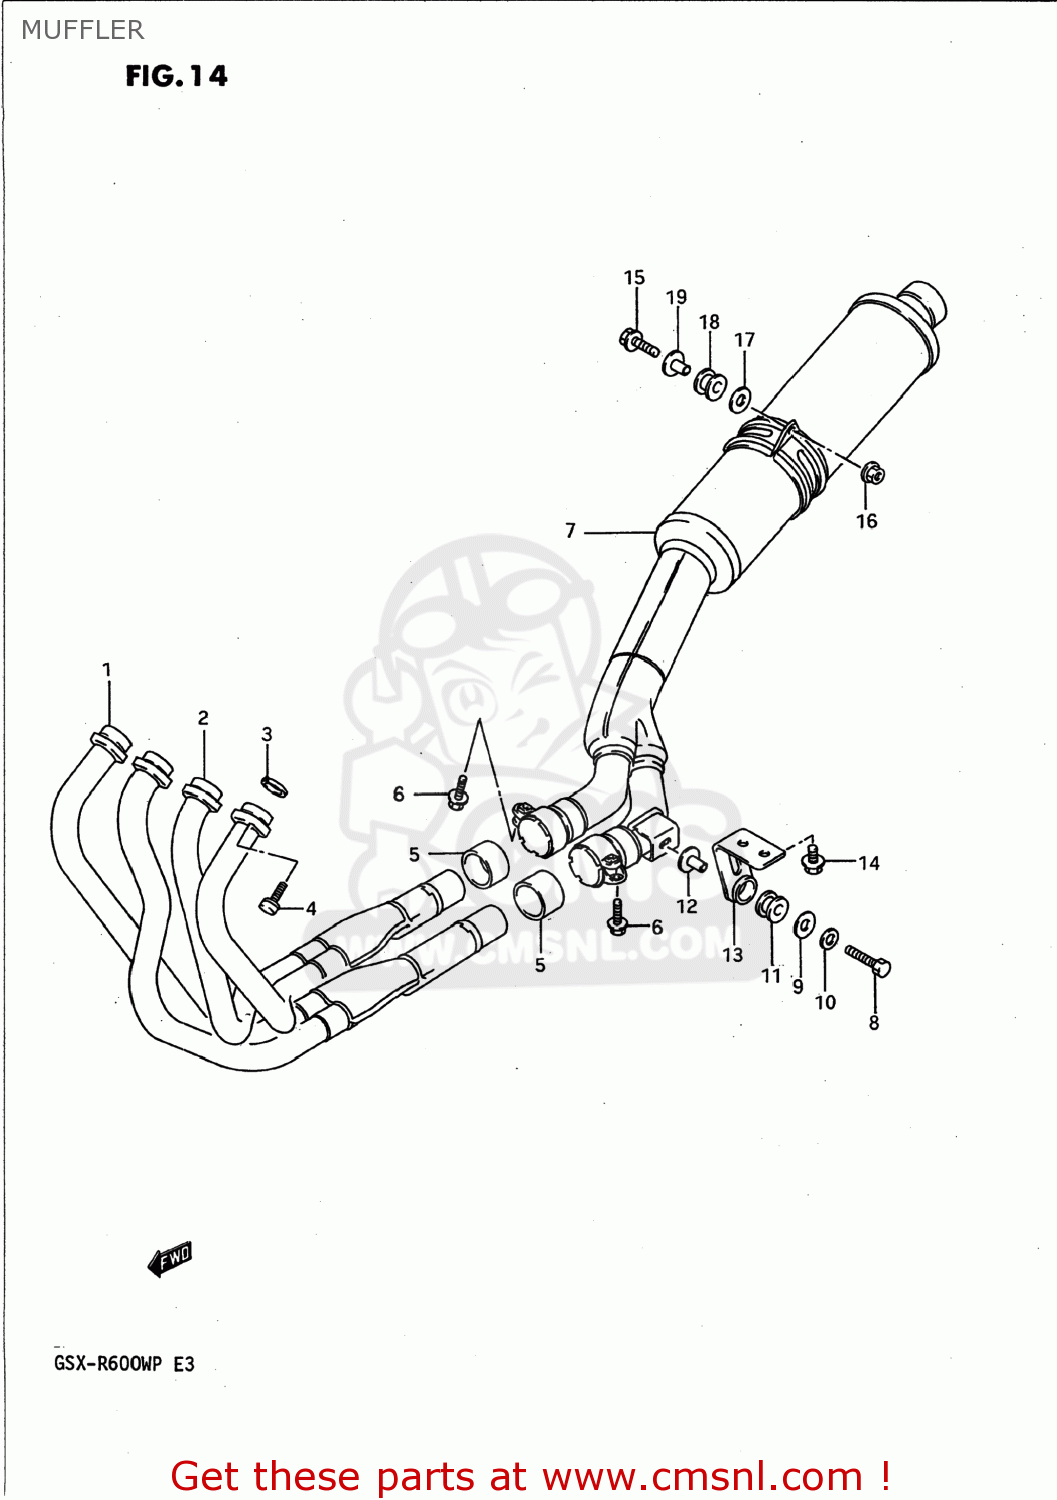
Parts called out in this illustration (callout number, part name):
1	PIPE,EXHAUST,RIGHT
2	PIPE,EXHAUST,LEFT
3	GASKET,EXHAUST PIPE
4	BOLT
5	CONNECTOR,MUFFLER
6	BOLT 8X40
7	MUFFLER ASSEMBLY
8	BOLT
9	WASHER (8.5X29X1.6)
10	LOCK WASHER
11	CUSHION
12	SPACER(8.6X12X24.2)
13	DAMPER,MUFFLER SUPPORT
14	BOLT
15	BOLT 8X45
16	NUT
17	WASHER (8.1X33X1.6)
18	CUSHION
19	SPACER(8.6X12X27.1)
